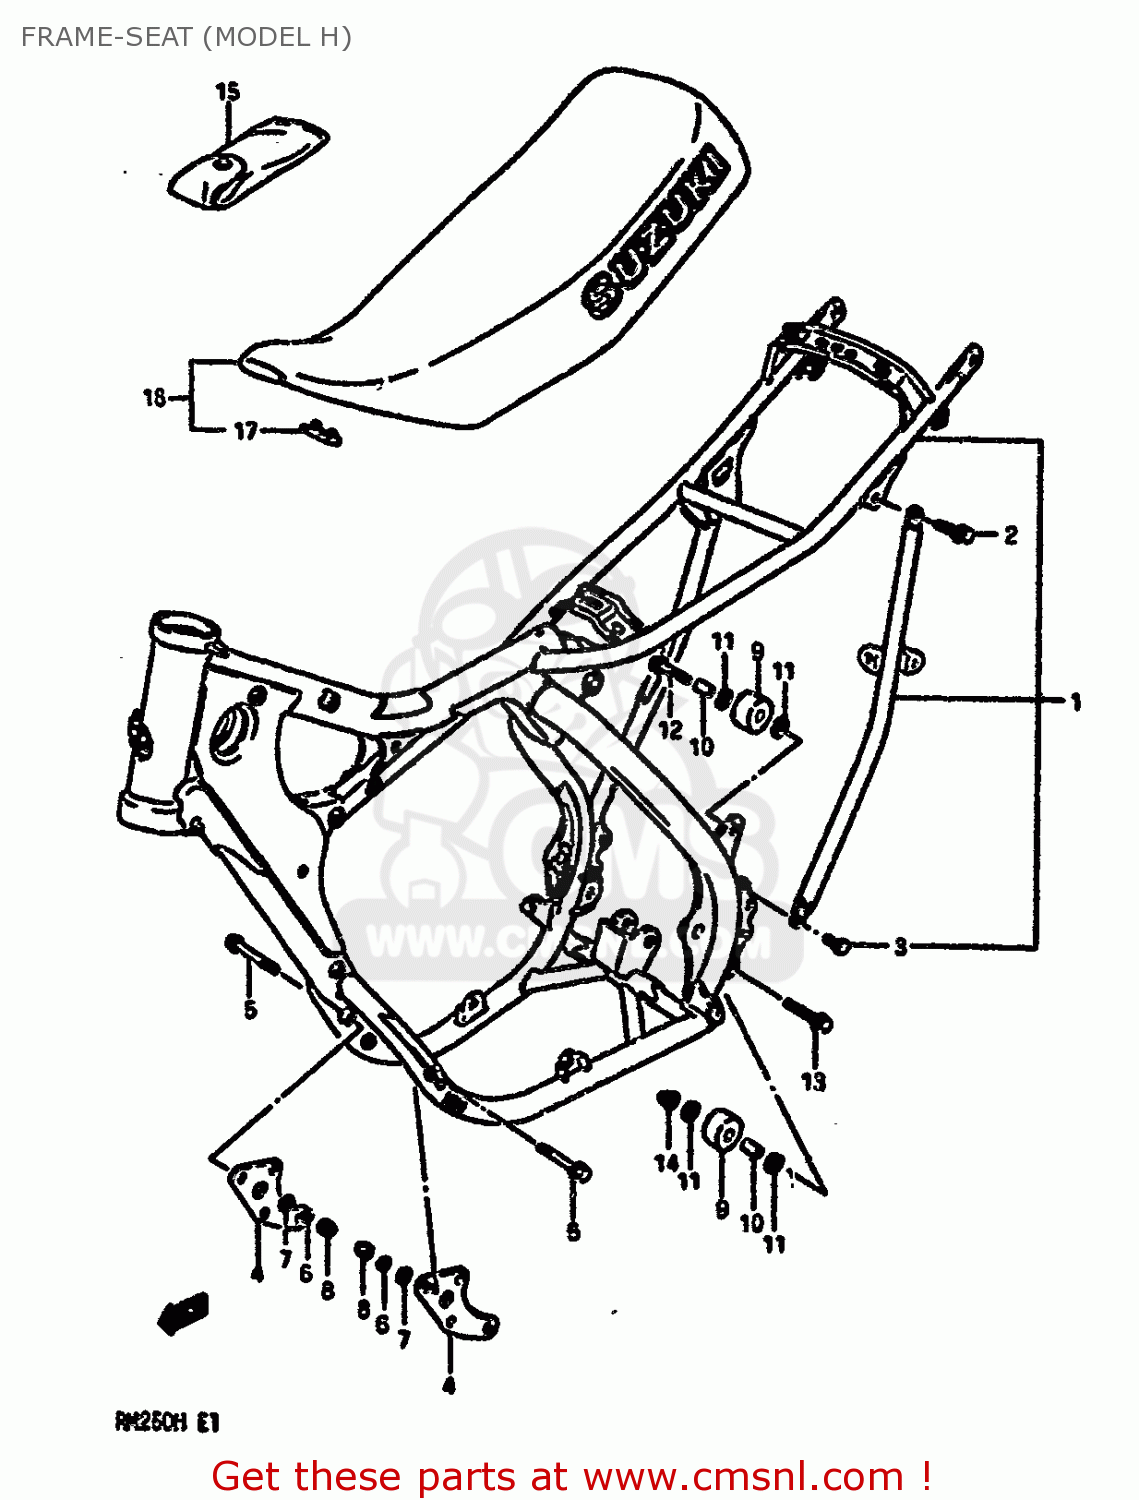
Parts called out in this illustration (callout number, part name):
1	FRAME
2	BOLT
3	BOLT
4	PLATE,ENGINE MOUNTING
5	BOLT 8X55
6	LOCK WASHER
7	WASHER
8	NUT
9	ROLLER,CHAIN CONTROL
10	SPACER (8.6X13.8X28)
11	WASHER
12	BOLT(8X75)
13	BOLT(8X50)
14	NUT
15	TOOL SET
16	SEAT SET
17	CUSHION
